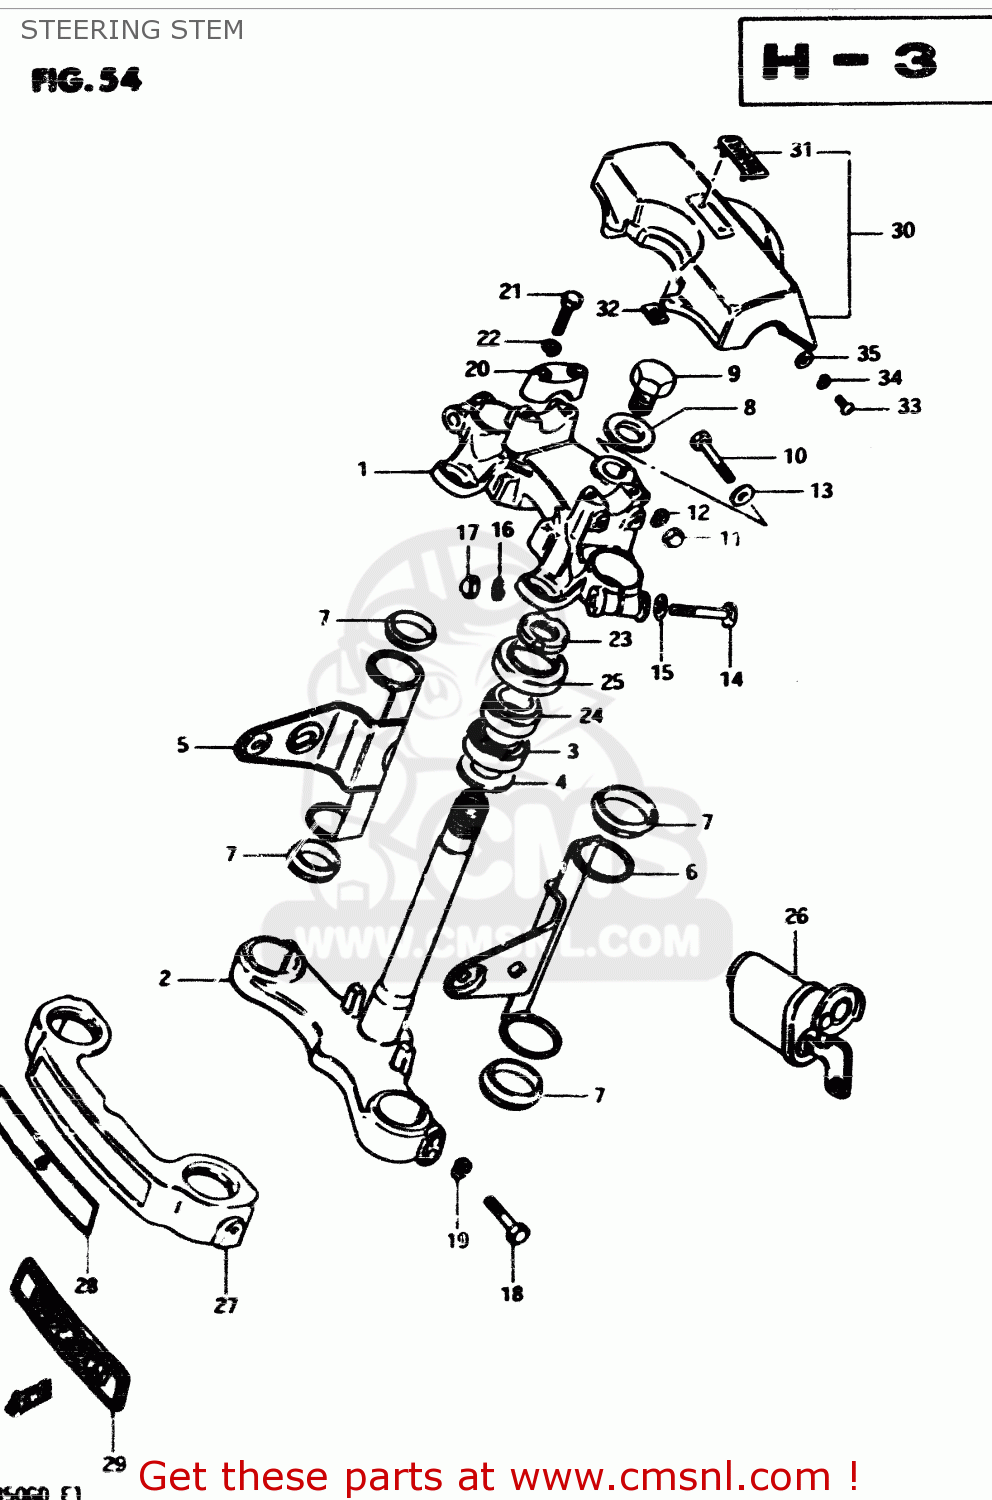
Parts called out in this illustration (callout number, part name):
1	HEAD,STEERING STEM
2	STEM,STEERING
3	BEARING
4	WASHER,THRUST
5	BRACKET,HEADLAMP,RIGHT
6	BRACKET,HEADLAMP,LEFT
7	CUSHION,HEADLAMP BRACKET
8	WASHER,STEERING STEM
9	NUT,STEM HEAD
10	BOLT 8X50
11	NUT
12	LOCK WASHER
13	WASHER
14	BOLT 10X55
15	WASHER
16	LOCK WASHER
17	NUT, LOWER LH
18	BOLT
19	LOCK WASHER
20	HOLDER,HANDLE(BLACK)
21	BOLT
22	LOCK WASHER
23	NUT,STEERING STEM
24	TAPER,ROLLER BEARING
25	DUST SEAL,STEERING UPR
26	LOCK ASSY, STEERING (NEIMAN TYPE EXECUTE
27	COVER,FRONT FORK
28	EMBLEM,FRONT FORK COVER
29	EMBLEM,FRONT FORK COVER
30	PAD,HANDLEBAR
31	EMBLEM,HANDLE COVER PAD
32	NUT
33	SCREW
34	LOCK WASHER
35	WASHER
